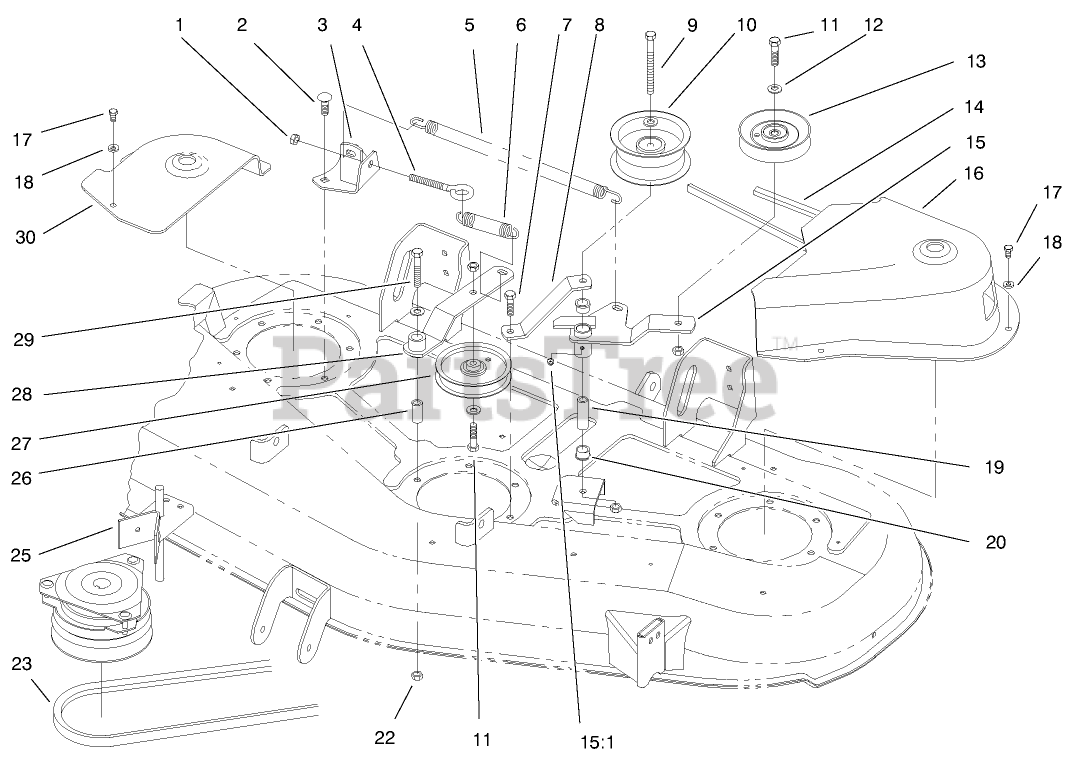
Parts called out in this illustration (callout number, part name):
1	NUT-LOCK, NI
2	SCREW-CARR
3	BRACKET-SPRING
4	BOLT-EYE
5	SPRING-EXTENSION
6	SPRING-EXTENSION
7	SCREW-HH
8	STRAP-SUPPORT
9	SCREW-HH
10	PULLEY-IDLER
11	SCREW-HH
12	WASHER-FLAT
13	PULLEY-IDLER
14	V-BELT
15	IDLER ARM ASSEMBLY
15:1	FITTING-GREASE
16	COVER-BELT, LH
17	SCREW-HWH
18	WASHER-FLAT
19	SPACER
20	BUSHING
22	NUT-HF
23	BELT - V
25	DECK UPSTOP ASSEMBLY
26	SLEEVE
27	PULLEY-IDLER
28	IDLER ARM ASM
29	SCREW-HH
30	COVER - BELT, RH
